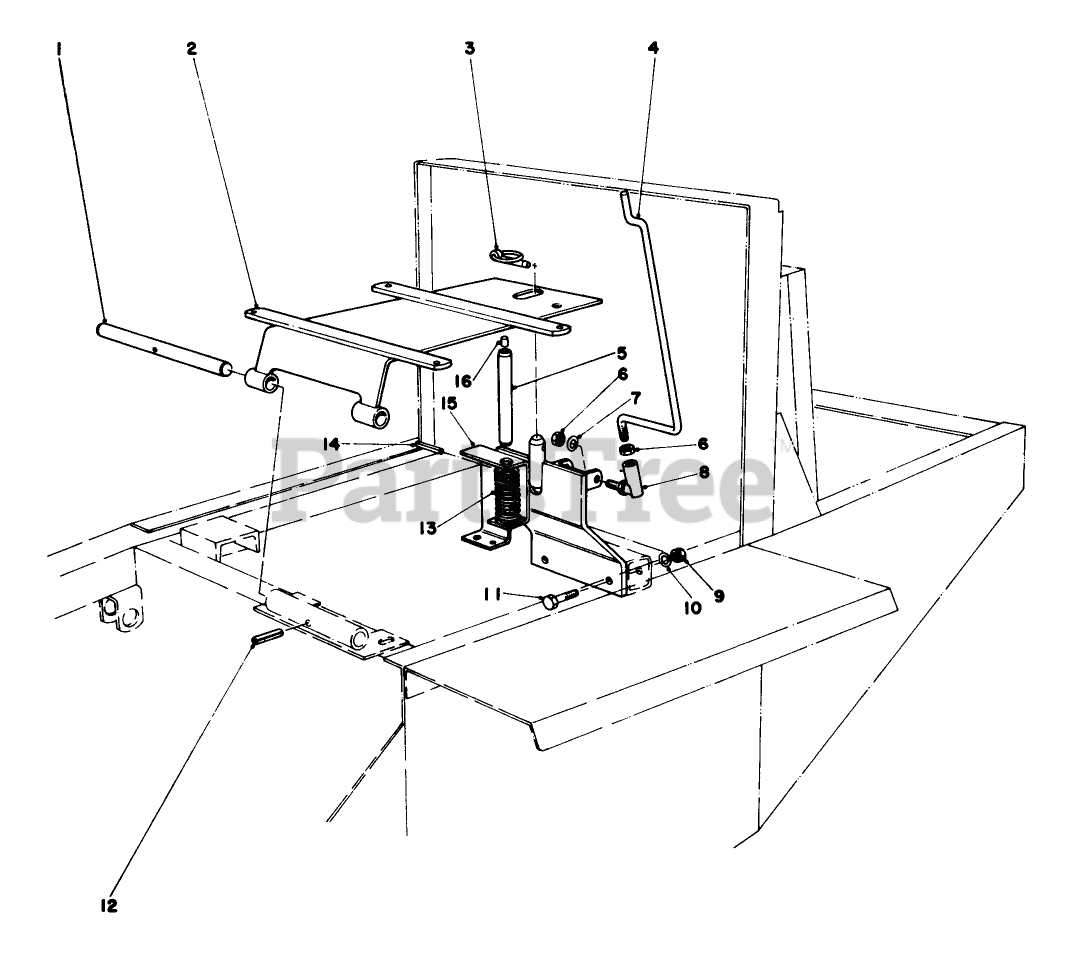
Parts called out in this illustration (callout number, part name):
1	SHAFT-PIVOT, SEAT
2	SEAT SUPT WA R
3	PIN-LYNCH
4	PROP SEAT
5	PIN-SWITCH, SEAT
6	NUT-JAM
7	WASHER-LOCK/SP
8	Ball Joint
9	NUT-HEX
10	WASHER-LOCK
11	SCREW-HH
12	PIN-ROLL, SLOTTED
13	SPRING-COMPRESSION
14	PIN-ROLL, SLOTTED
15	Bracket-Seat Support
16	PIN-PEDAL
